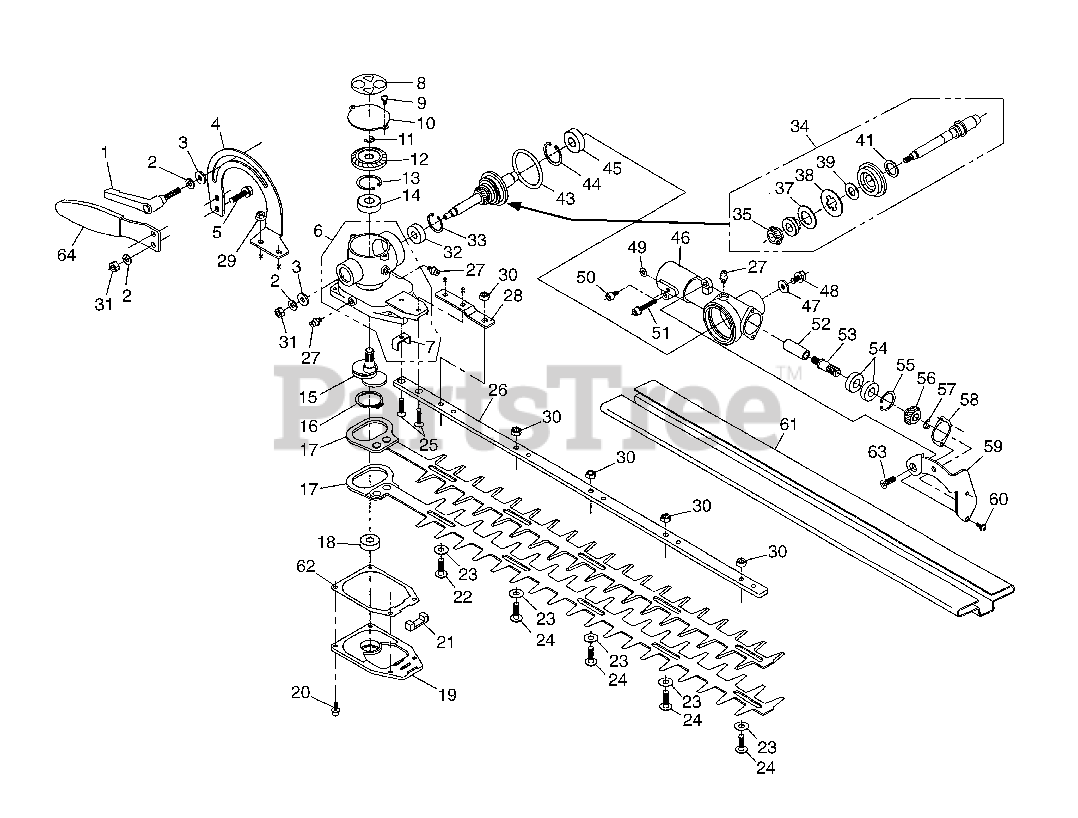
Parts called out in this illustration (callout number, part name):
1	CLAMP LEVER M6X16MM
4	ANGLE ADJUSTER
6	CASE(A) SET
10	COVER(A)
13	RING,SNAP M26x1.2 RP-318013340
15	CRANKSHAFT
16	RING, SNAP, M28 x 1.5
18	BEARING
22	SCREW(R3873,388411750&11770
24	SCREW.L17
25	SCREW.5X20
26	GUIDE PLATE
33	RING, SNAP, M22 x 1.2
34	KIT,SHAFT(R678213600,10,13340)
35	GEAR (C)
37	WASHER, SPRING
44	RING,SNAP M26x1.2 RP-318013340
46	CASE (B)
48	BOLT M6x12 (RPLS 022510612)
50	BOLT M5X10
51	BOLT M5X30
53	GEARSHAFT(B)
55	RING, SNAP, M22 x 1.2
61	COVER
